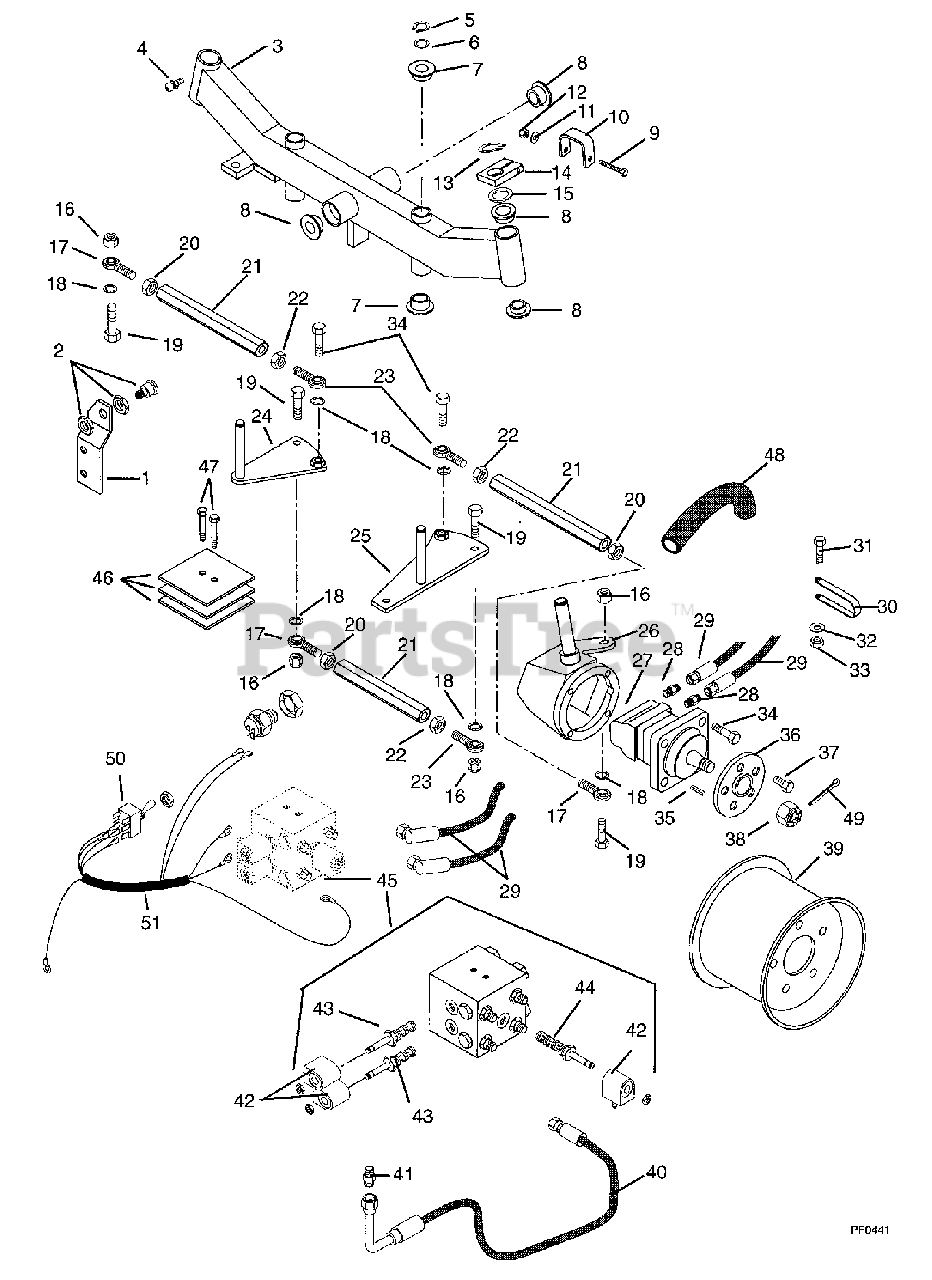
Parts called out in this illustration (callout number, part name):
2	Safety Switch
3	Axle Weldment
4	Fitting Lube .25-28 x .256
5	Ring-Retaining-External .689 x .077
6	Bearing-Needle-Thrust .752 x 1.24 x .031
7	Bushing-Flange .762 x 1.0 x .580 x 1.48
8	Bushing-Flange 1.020 x 1.385 x .75 x 1.75
9	Bolt-Hex .25-20 x 2.75 Grade 5
10	Bracket, Hose Loop
11	Washer-Flat-Steel .281 X .62 X .065
12	Nut-Locking .25-20
13	Ring-Retaining-External .906 x .078
14	Bracket Support
15	Washer-Hardened Thrust 1.002 x 1.552 x .030
16	Nut-Locking-Center .50-13 Grade 5
17	Assembly, Rod End Right Hand
18	Spacer .520 x .625 x .125
19	Bolt-Hex .50-13 x 2.00 Grade 5
20	Nut-Jam .50-20 Grade 2
21	Rod, Tie
22	Nut-Jam .50-20 Left Hand Grade 2
23	Assembly, Rod End Left Hand
24	Weldment, Steering Idler
25	Weldment, Steering Arm
26	Spindle Weldment Left Hand
26	Spindle Weldment Right Hand
27	Eaton 2000 Wheel Motor
28	Adapter, Hydraulic
29	Assembly, Hydraulic Hose
30	Clamp, Nylon
31	Bolt-Hex .38-16 x 1.00 Grade 5
32	Washer-Flat-Steel .406 x .812 x .065
33	Nut-Locking-Center .38-16
34	Bolt-Hex .50-13 x 1.50 Grade 5
35	Key-Square .313 x 1
37	Screw-Hex-Tapping .500-20 x .62
38	Nut-Hex Slotted 1-20
40	Assembly, Hydraulic Hose
41	Adapter, Hydraulic
42	Coil, Solenoid
43	Valve, 3-Way 12VDC Directional
44	Valve, 4-Way 12VDC Directional
45	Hydraulic Manifold Assembly
47	Bolt-Hex .31-18 x 1.25 Grade 5
48	Sleeve 18"
49	Pin-Cotter .12 x 2.0
50	Power Switch, four Wheel Drive
51	Wire Harness, 4 Wheel Drive
